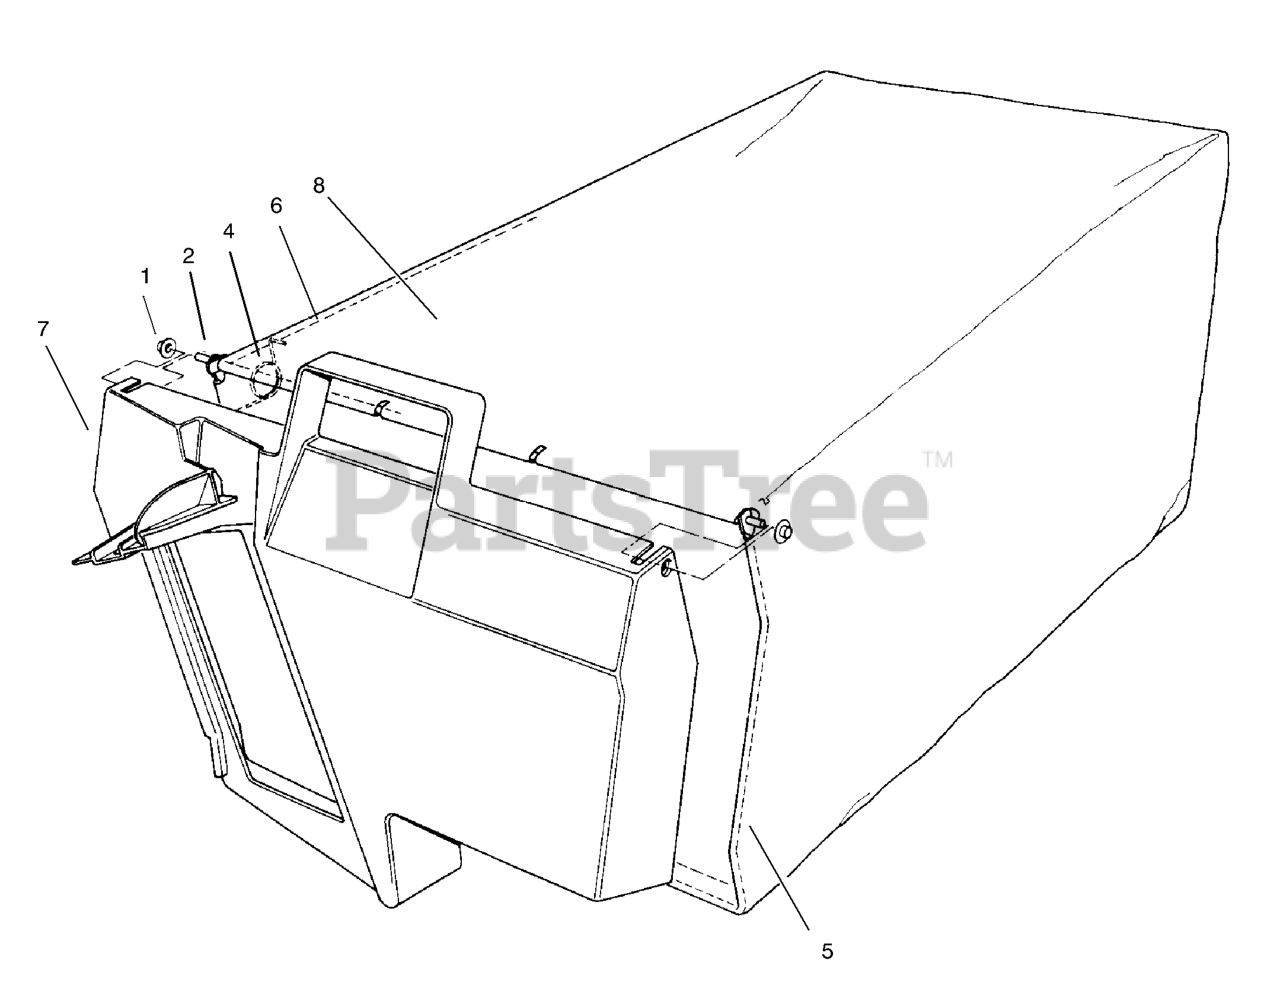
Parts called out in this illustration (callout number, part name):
1	NUT-PUSH
2	HINGE-DOOR, BAG
5	FRAME-BAG
